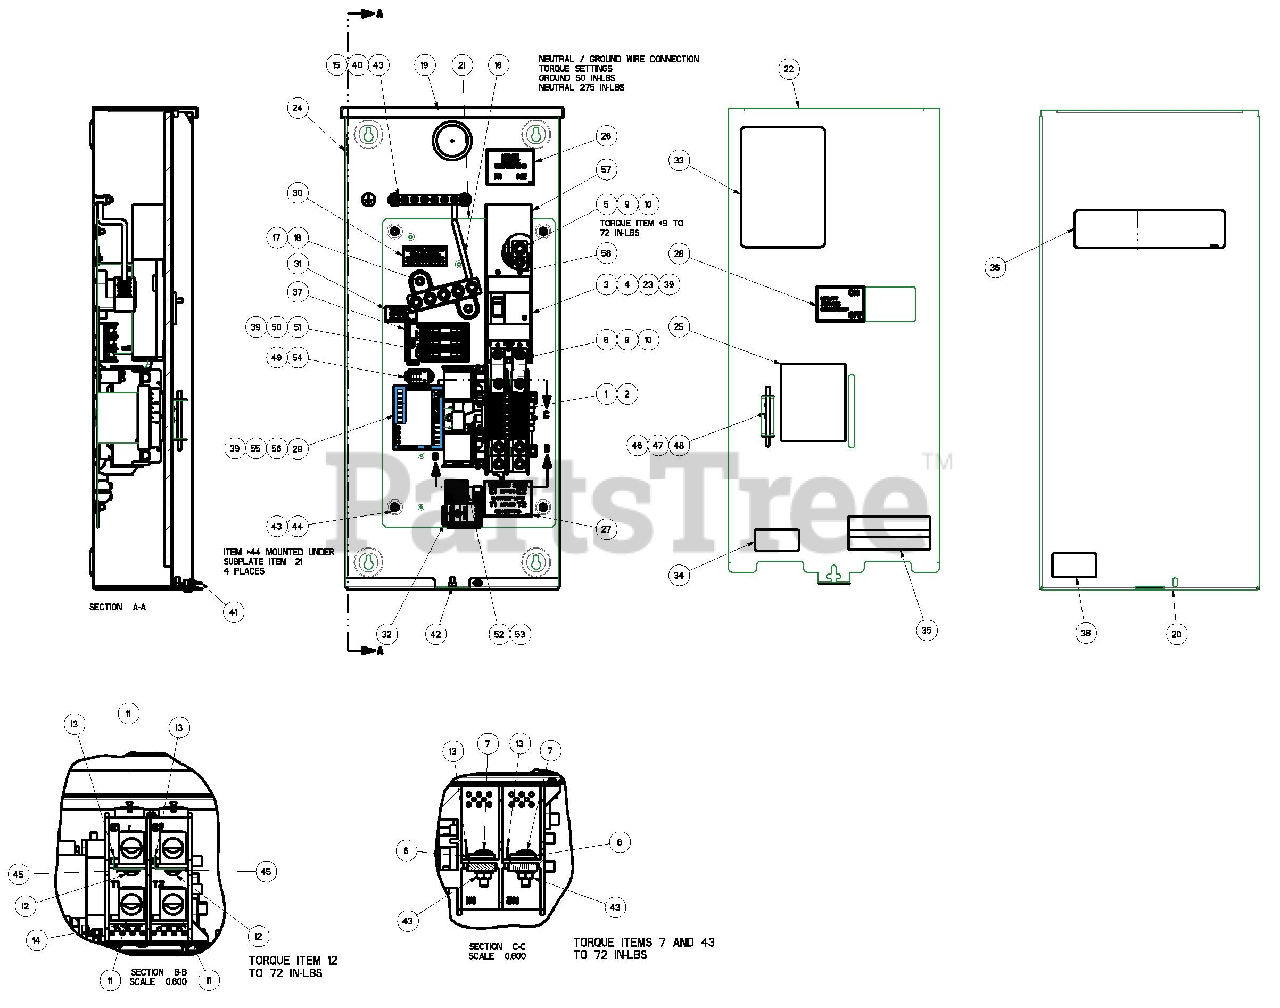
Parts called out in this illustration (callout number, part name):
1	XFRSW HSB 200 A 2P 250V
2	SCREW HHTT M5 - 0 . 8 X 10 BP
3	CB 200 A 2POLE 240V 225AF
4	SCREW RHM # 8 - 3 2 X 2 - 1 / 2
5	LUG S LDLSS 350 MCM-6 AL/CU
6	SPACER , 200 AMP TRANSFER SWITCH
7	BOLT CARR 1/ 4 - 2 0 X 1
8	BUSBAR 200 A TRANSFER SW Nl , N2
9	SCREW SHC M8 - 1 . 2 5 X 20 G8
10	WASHER LOCK M8 - 5 / 16
11	LUG SLDLSS 250 - # 6 AL/CU
12	SCREW BHSC 1 / 4 - 2 0 X 3/8
13	90 DEGREE DN SPADE CONNECTOR
14	STRAIGHT SPADE CONNECTOR
15	LUG SLDLSS 2 / 0 - # 1 4 X # 10- 3 2 X . 1 25
16	WIRE NEUTRAL/GND CONNECTION
17	ASSY -NEUT BLK 200A W/TAP
18	SCREW HHTT M 6 - 1. 0 X 12 Z INC
19	ENCLOSURE 200 A SE XFRSW RAW
20	COVER, 200 A SE XFRSW RAW
21	SUB PLATE, 200 A SE XFER SW
22	COVER IN SIDE 200A SE XFER SW RAW
23	CB RISER BRACKET 200A GENERAC
24	DECAL, XFER SW SE 200A 120/240
25	DECAL WARN MANUAL OPER HANDLE
26	DECALS, SERVICE ENTRANCE
27	DECALS, SERVICE ENTRANCE
28	DECALS, SERVICE ENTRANCE
29	ASSY LOAD SHED W/VSCF
30	DECAL, NEUTRAL CONNECTION
31	DECAL, FUSE REPLACEMENT
32	DECAL CUSTOMER CONN RTS
33	DECAL TEST SEQUENCE 100 - 200A SE
34	DECAL LIVE CIRCUIT ENG/FRN/SPN
35	DECAL TERMINAL SHOCK HZD Bl
36	DECAL RTS TRANSFER SW GENERAC
37	DECAL UTILITY LOAD SENSE 240V
38	DECAL NEC COMPLIANCE
39	SCREW HHTT M4 - 0 . 7 X 10 BP
40	WASHER LOCK EXT 1/4 STL
41	SCREW THUMB 1/ 4 - 2 0 X 1/2 W/SHLD
42	NUT HEX 1/ 4 - 2 0 SS
43	NUT HEX FL WHI Z 1 / 4 - 2 0
44	WASHER FLAT 1/4-M6 Z 1NC
45	WASHER LOCK M 6 - 1/4
46	BRACKET, ARM EXTENDER
47	RIVET POP . 156 X . 362 AL
48	PIN ARM EXTENDER
49	RELAY PNL 12 VDC DPDT 10A@240VA
50	FUSEBLOCK 30A 600V 3POS W/SO
51	FUSE 5A X BUSS
52	TERM BLOCK 3P UL 12 - 20AWG
53	SCREW PHTT M3 - 0 . 5 X 25
54	SCREW HHTT M3 - 0 . 5 X 6 BP
55	BRACK E T LOAD SHED 200A RTS
56	CHANNEL SNAPTRACK 7 6 . 2 X 101 . 2
57	CB TERMINAL COVER 2 POLE 240V
58	SCREW PFH 4 - 24 X 5/16 TCS
